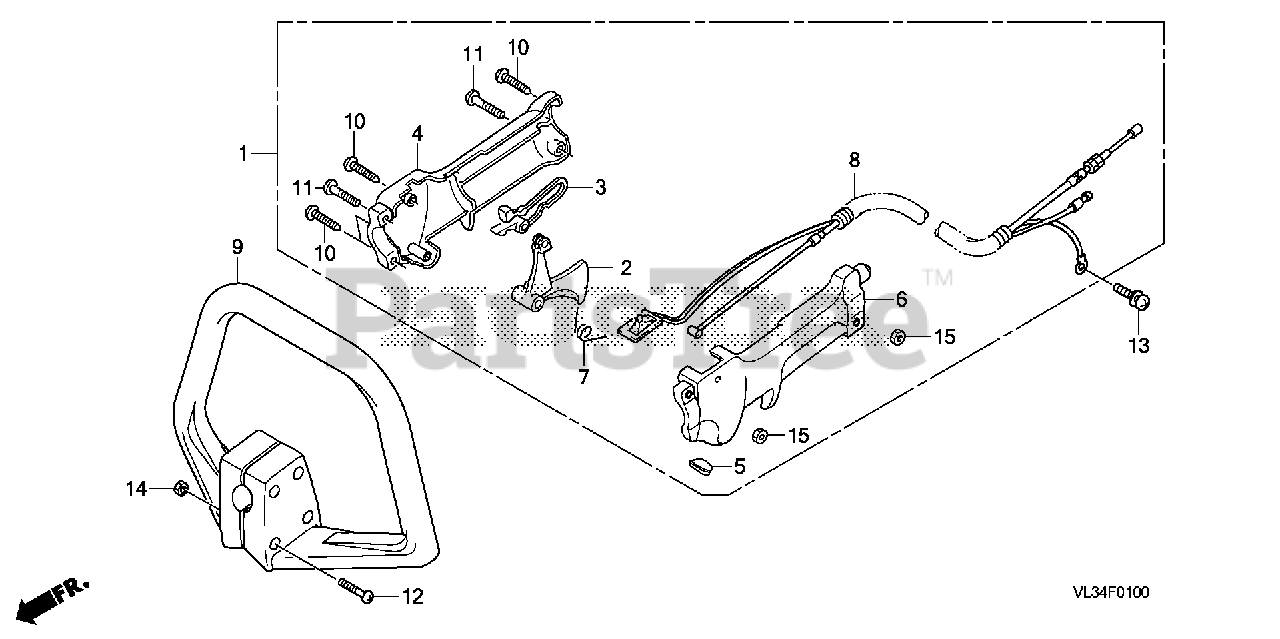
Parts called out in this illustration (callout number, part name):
1	LEVER ASSY., THROTTLE (L26)
2	LEVER, THROTTLE (YELLOW)
3	LEVER, THROTTLE LOCK (YELLOW)
4	GRIP, R. THROTTLE LEVER
5	CAP, THROTTLE LEVER
6	GRIP, L. THROTTLE LEVER
7	SPRING, THROTTLE LEVER
8	WIRE HARNESS ASSY.
9	HANDLE, LOOP
10	SCREW, TAPPING (4X20)
11	SCREW, PAN (5X20)
12	SCREW, PAN (5X30)
13	SCREW-WASHER (5X12)
14	NUT, HEX. (5MM)
15	NUT, HEX. (5MM)
